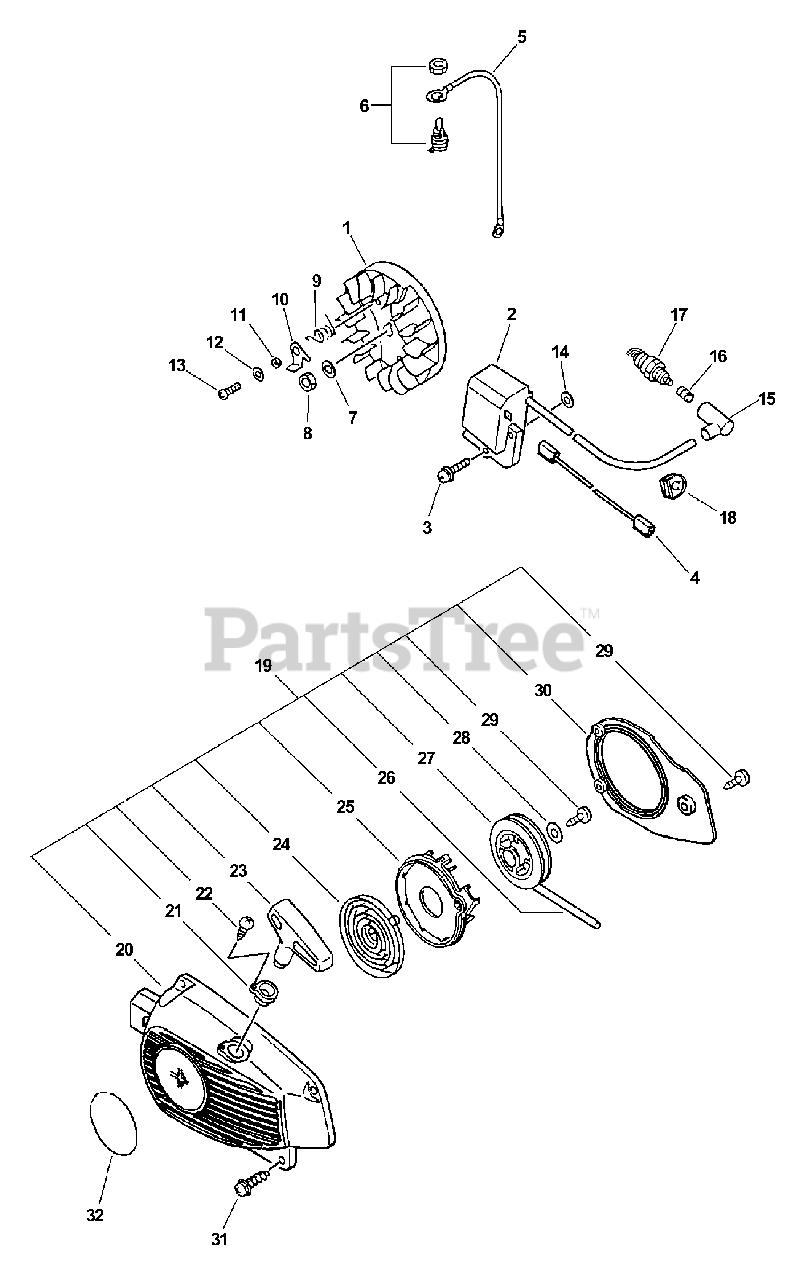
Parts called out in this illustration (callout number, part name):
1	FLYWHEEL
2	COIL, IGNITION
3	SCREW - 5X20
3	SCREW - 5X22
4	LEAD - IGNITION
5	LEAD - GROUND
6	IGNITION SWITCH KIT
7	WASHER - 8
8	NUT - 8
9	SPRING, RETURN
10	PAWL, STARTER
11	SPACER
12	WASHER - 5
13	SCREW - 5X12
14	SPACER
15	CAP, SPARK PLUG
16	TERMINAL, SPARK PLUG CAP
17	SPARK PLUG -- BPM-7A
17	SPARK PLUG -- BPMR-7A
18	GROMMET
19	STARTER ASSY
20	CASE, STARTER
21	GUIDE, ROPE
22	SCREW - 3X14
23	GRIP, STARTER
24	REWIND SPRING ASSY
25	PLATE, STARTER
26	ROPE, STARTER - 3X850
27	REEL, ROPE
28	WASHER
29	SCREW - 4X14
31	SCREW - 4X16
32	LABEL - ECHO
